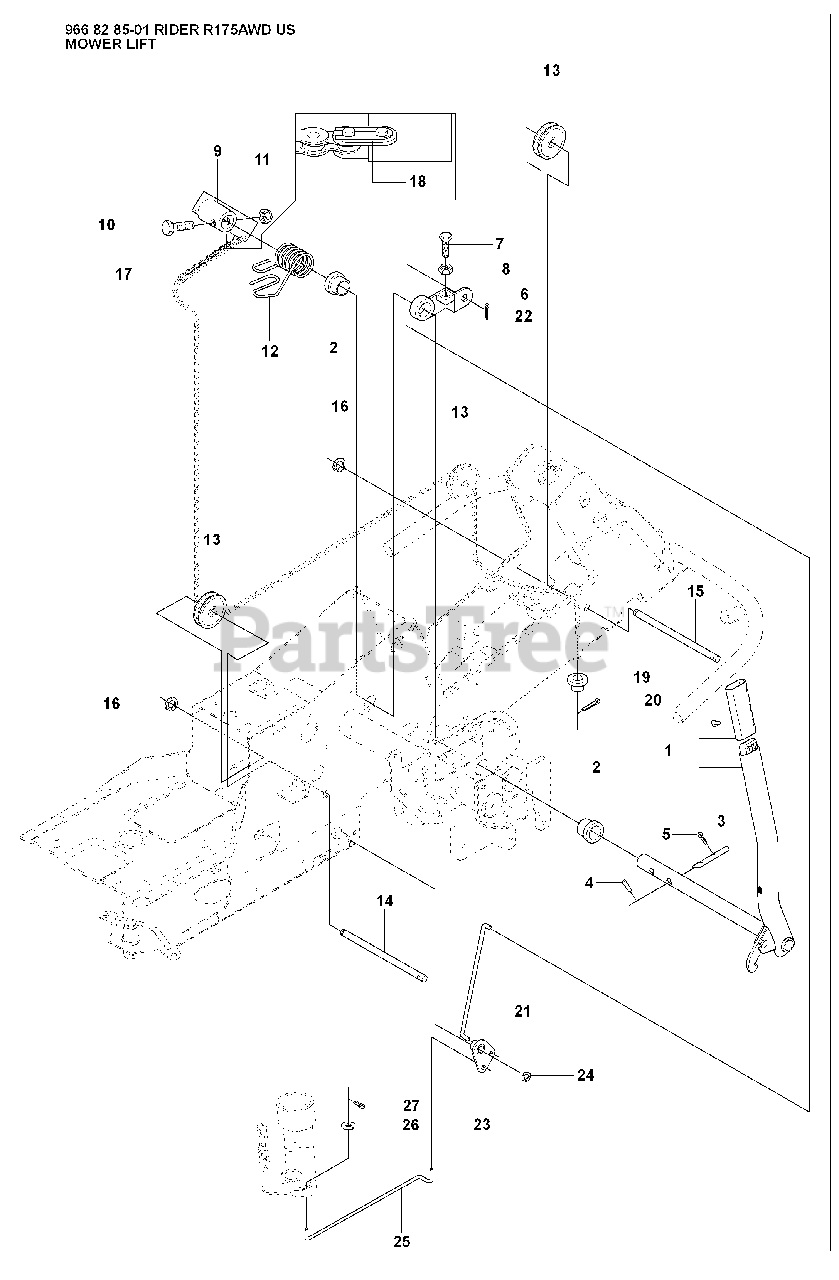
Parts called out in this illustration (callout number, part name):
1	LIFTING LEVER ASSY
2	BEARING FLANGE
3	RP PIN
6	LEVER CLUTCH
8	NUT
11	Lock Nut, Fiber M12 DIN 985 Z/P
20	COTTER PIN
21	CONNECTION ROD
24	RETAINING RING
25	CONNECTION ROD
